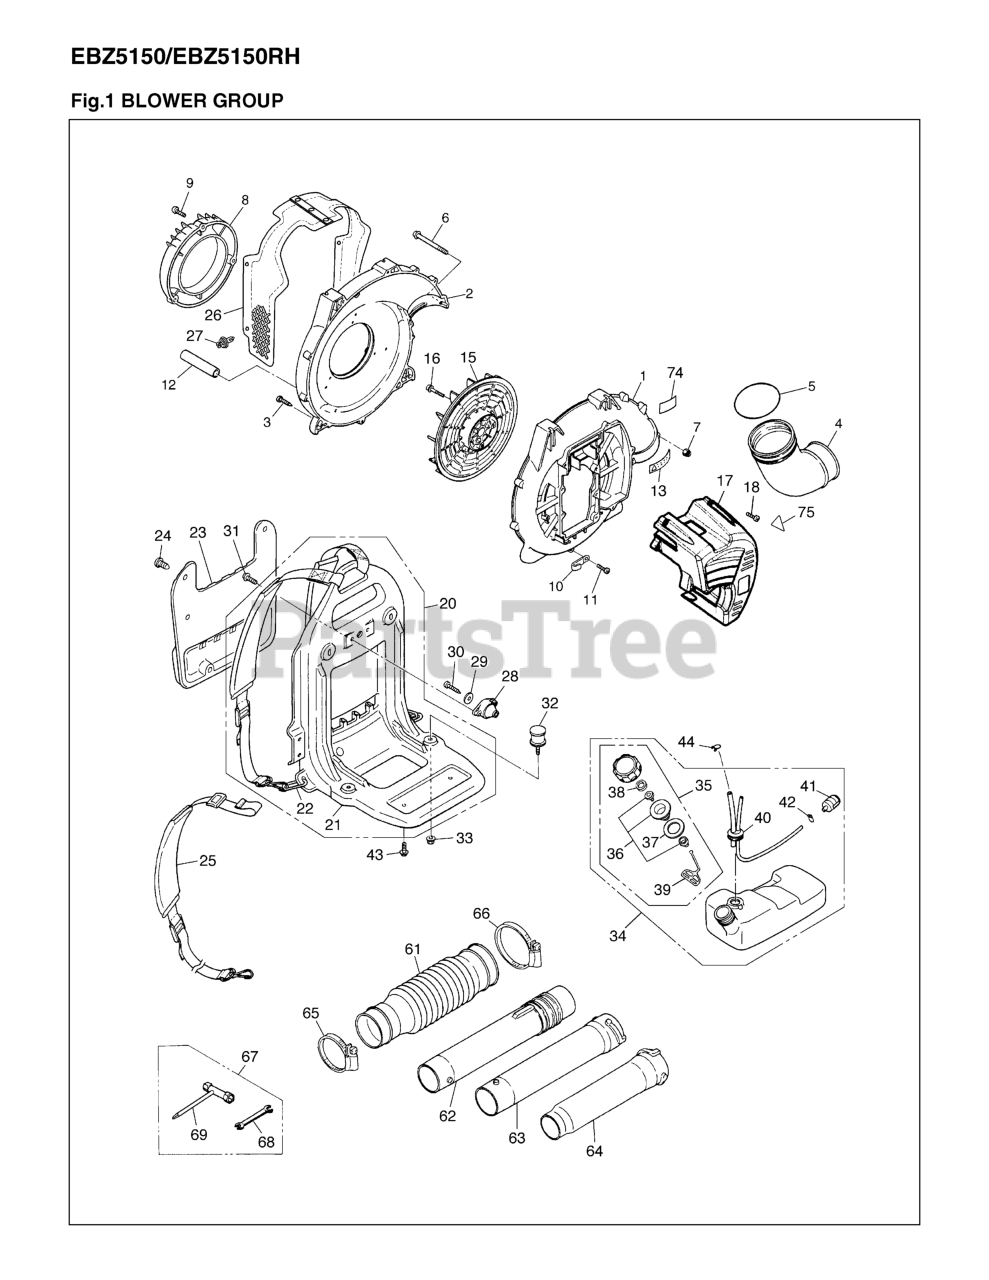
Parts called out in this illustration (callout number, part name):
1	CASE, VOLUTE
2	COVER, VOLUTE
3	SCREW
4	ELBOW
5	O-RING
6	BOLT,TORX, M5X70
7	NUT (B)
8	FUNNEL
9	SCREW
10	CLAMP
12	TUBE (RPLS. 07270-01507)
13	LABEL CE CAUTION
15	FAN
16	BOLT
17	ENGINE COVER
18	SCREW
20	FRAME ASSY
21	FRAME COMP
22	RING (REPLACES -21120)
23	PAD
24	CLIP (RPLS 3490-21320)
25	BAND ASSY
26	NET COMP
27	CLIP
28	DAMPER, UPPER
29	WASHER
30	SCREW (RPLS T4970-54010)
31	SCREW TORX
32	DAMPER, LOWER
33	NUT, M6
34	TANK ASSY
35	CAP ASSY
36	HOLDER (REPLACES -85230)
37	PACKING
38	FILTER
40	PIPE COMPLETE
41	FILTER ASSY
42	CLIP (REPLACES 2841-31280)
43	SCREW TORX
44	CLIP
61	HOSE
62	SWIVEL-JOINT (REPLACES -51200)
63	PIPE, STRAIGHT
64	KIT, NOZZLE (USE 2756-51221)
67	TOOL-SET
68	SPANNER, 8 X 10 (RPLS 2540- )
74	LABEL, SOUND
75	LABEL, HOTMARK
